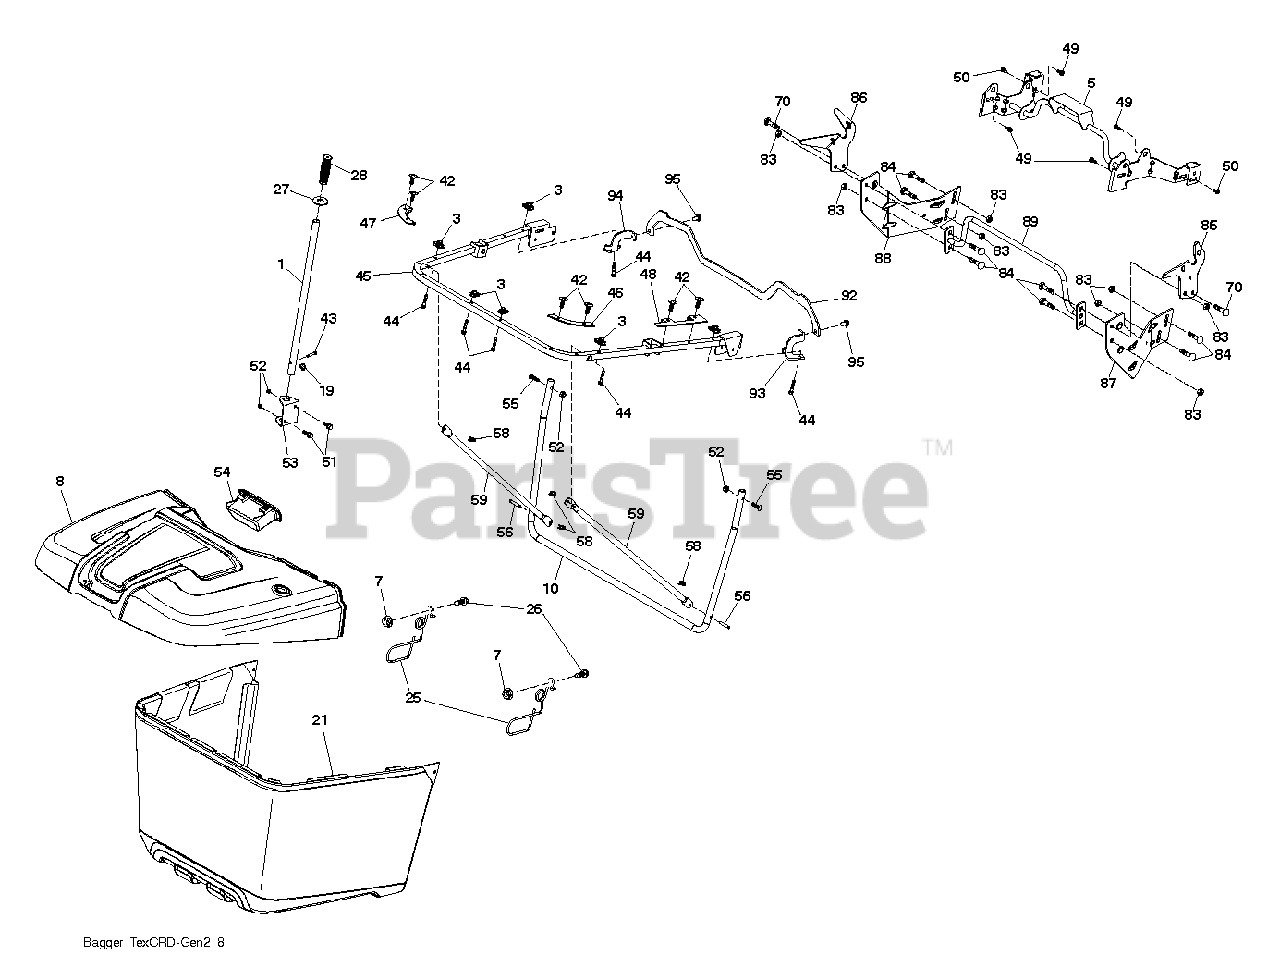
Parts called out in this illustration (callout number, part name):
1	TUBE.PNT.HDL.BAGGER.
3	1/4-20 U NUT
7	NUT T
19	PIN.COTTER.5/16.BOW TI
26	SCREW HEX CRT
28	GRIP.HANDLE.BLACK
43	RIVET,DRILLED
49	BOLT, SHOULDER 5/16-18
50	BOLT, 5/16-18 X 1 3/4
52	NUT.71038.31-18.HEX.NYLOCK
56	PIN.CLEVIS.183
58	RETAINER CLIP PM
70	SCREW, 3/8-16X3/4
83	NUT
92	BRACKET.PNT.BAGGER.TOP.SUPPORT
93	BRACKET.PNT.RH.SUPPORT.ATTACH
94	BRACKET.PNT.LH.SUPPORT.ATTACH
95	SCREW
